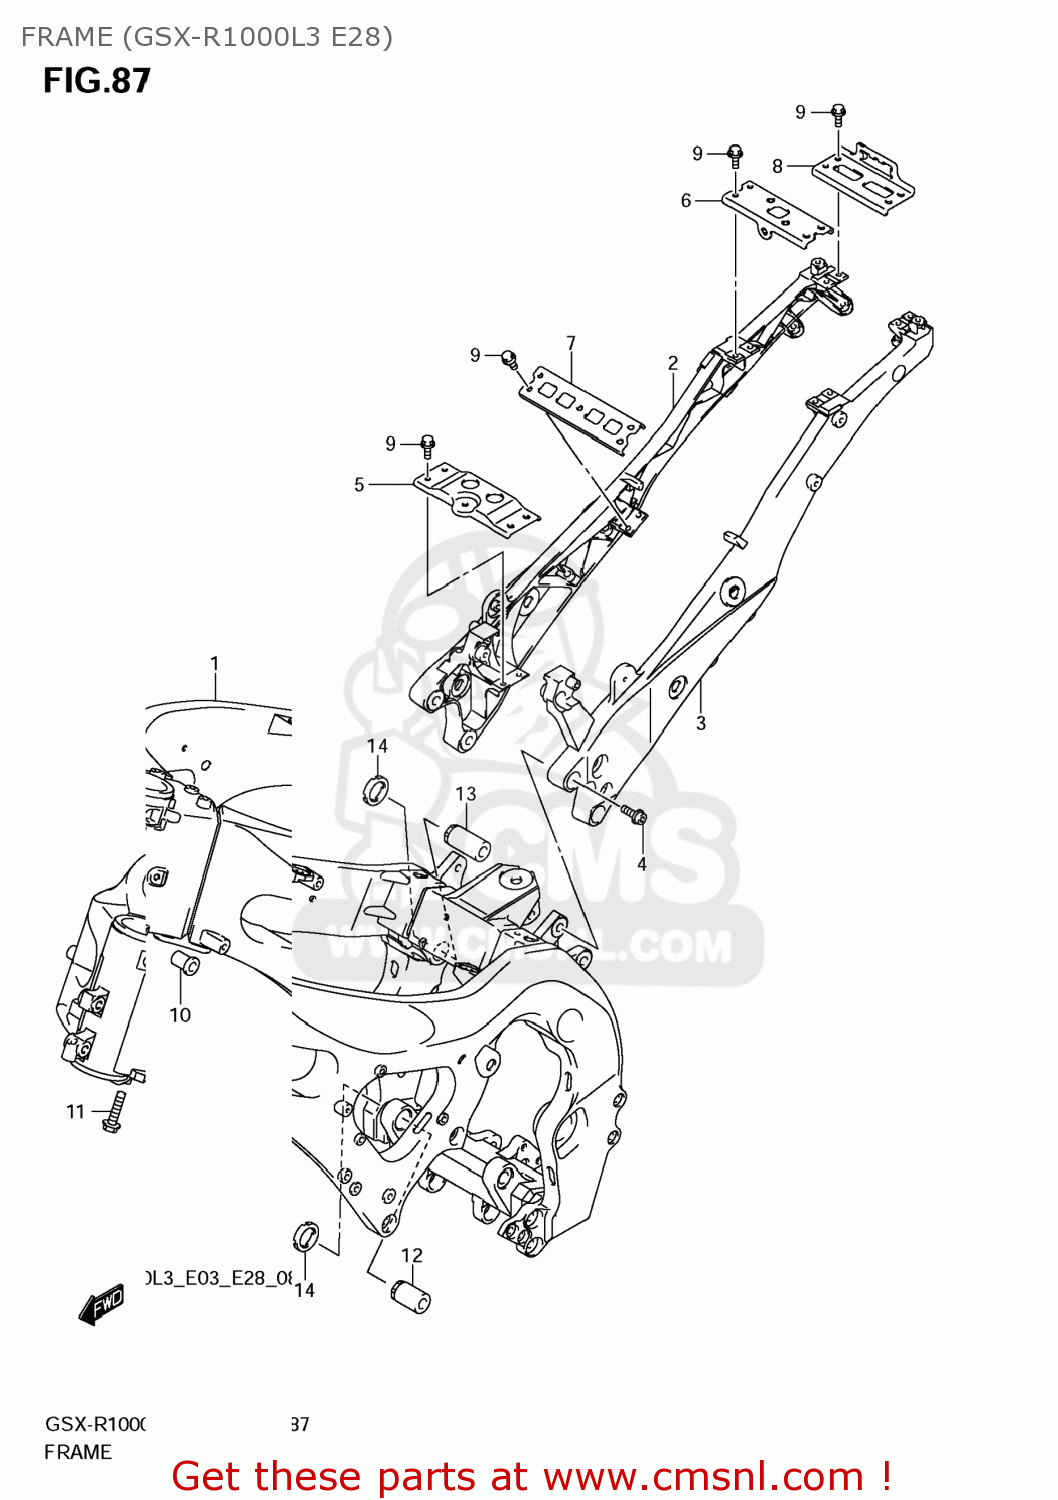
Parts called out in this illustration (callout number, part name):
1	FRAME(BLUE)
2	RAIL,SEAT,R
3	RAIL,SEAT,L
4	BOLT,SEAT RAIL
5	BRIDGE,SEAT RAIL FR
6	BRIDGE,SEAT RAIL UPR
7	BRIDGE,SEAT RAIL LWR
8	BRIDGE,SEAT RAIL RR
9	BOLT(6X12)
10	SPACER,ENGINE MOUNTING
11	BOLT(8X35)
12	BOLT,CRANK CASE ADJUST
13	BOLT,CRANK CASE ADJUST UPR
14	NUT,CRANK CASE ADJUST BOLT
